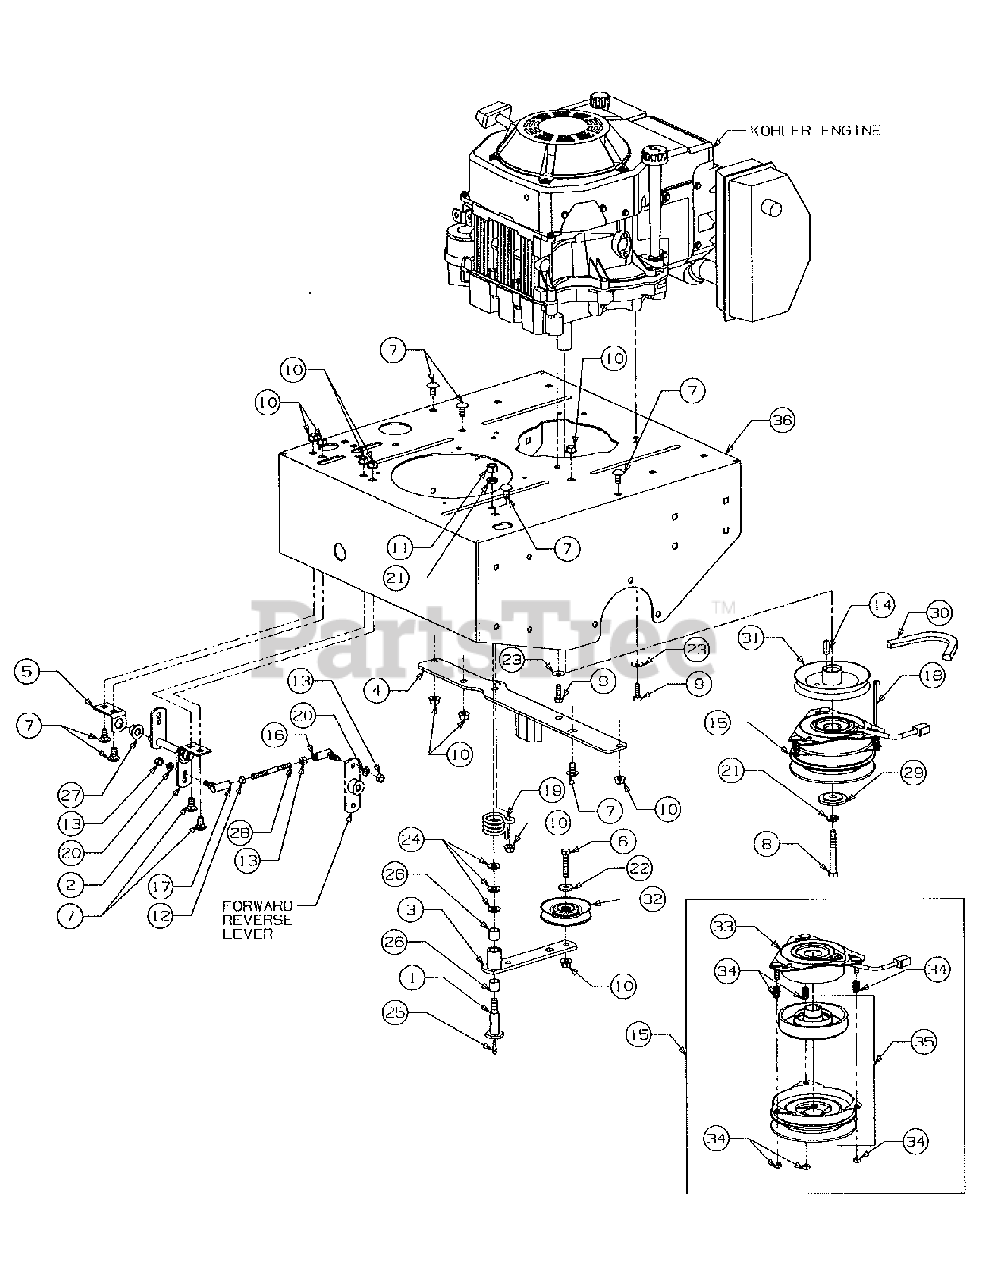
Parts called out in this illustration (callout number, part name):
1	Bolt, Shoulder
2	Lever, F/R Control
3	Arm, Ass'y Idler
4	Retainer, PTO Clutch
5	Bracket,Lever Angle
6	Screw, Hex Cap, 3/8-15 x 1.75 Lg Gr5
7	Bolt, Sht Nk Carriage, 3/8-16 x .75 Lg Gr5
8	Screw, Hex Cap,M10 x 1.5 x 80mm Lg
9	Screw, Hex Cap, M8 x 1.25 x 25mm Lg
10	Nut, Hex Flanged Lock, 3/8-16
11	Nut, Hex, 7/16-14 Gr5
12	Nut, Hex Jam, 5/16-24 LH Thread
13	Nut,Hex, 5/16-24 Gr5
14	Key Square, 1/4 x 1.0 Lg
15	Clutch Ass'y PTO
16	Ball Joint, 5/16-24
17	Ball Joint, 5/16-24 LH Thread
18	Cable Tie
19	Spring, Torsion
20	Washer, Lock 5/16
21	Washer, Lock 7/16
22	Washer Special, .378 x 1.00 x .125 Thk
23	Washer, Bell, .340 x .872 x .060 Thk
24	Washer, FLat, .469 x .872 x .105 Thk
25	Fitting, Lube
26	Bearing Sleeve
27	Bearing, Hex FLange
28	Rod Control
29	Spacer, Clutch
30	Belt, Transmission 1/2 x 40.0 Lg
31	Pulley, Engine
32	Pulley, V-Idler
33	Field Ass'y
34	Mounting Accessories
35	Kit, Armature and Rotor
36	Deck w/Graphics, Engine Mtg
